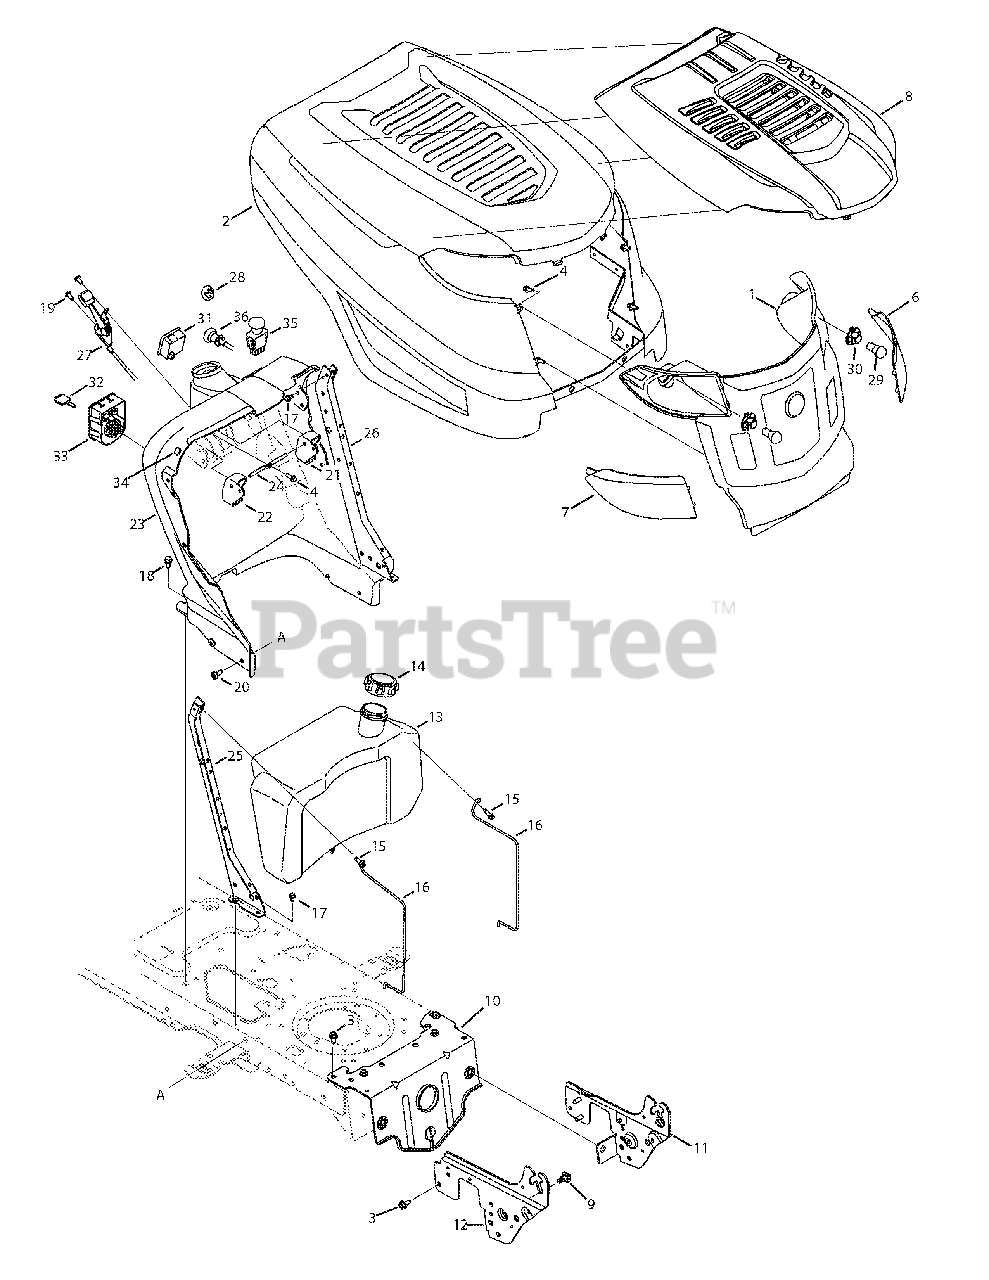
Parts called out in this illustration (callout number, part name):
1	Grill Assembly
2	Hood, K-Style
3	Screw, 5/16-18, 0.625
4	Self-tapping Screw, 1/4-15 x.75
6	Headlight Lens (LH)
7	Headlight Lens (RH)
8	TB Hood Scoop
9	Shoulder Screw,.43 x.29
10	Pivot Bar Bracket
11	Pivot Support Bracket, LH (42" Dk.)
11	Pivot Support Bracket, LH (50" Dk.)
12	Pivot Support Bracket, RH (42" Dk.)
12	Pivot Support Bracket, RH (50" Dk.)
13	Fuel Tank, 2.5 gal.
14	Fuel Tank Cap
15	Screw, 1/4-20, 0.750
16	Gas Tank Support Rod, RH
16	Gas Tank Support Rod, LH
17	Screw, 1/4-20, 0.500
18	Screw, 5/16-18 x 0.500
19	Screw, 1/4-14 x.625
20	Screw, 5/16-18 x.75
21	Parking Brake Button
22	Cruise Control Button
23	Dash Panel w/ Manual PTO
23	Dash Panel w/ Electric PTO
24	Brake/Cruise Pivot Rod
25	RH Dash Support Plate
26	LH Dash Support Plate
27	Throttle/Choke Cntrl. Cable (Single)
27	Throttle Cable (Twin Cyl.)
28	Choke Plug
29	Headlamp, 12V
30	Lamp Socket
31	Systems Ind. Monitor w/ Amtr.
31	Service Reminder / Hour Indicator
32	Ignition Key w/ plastic cover
33	Module, Ignition Switch
34	Rubber Bumper, .62 dia. x .3
35	Electric PTO Switch
36	Choke Control Cable (Twin Cyl.)
